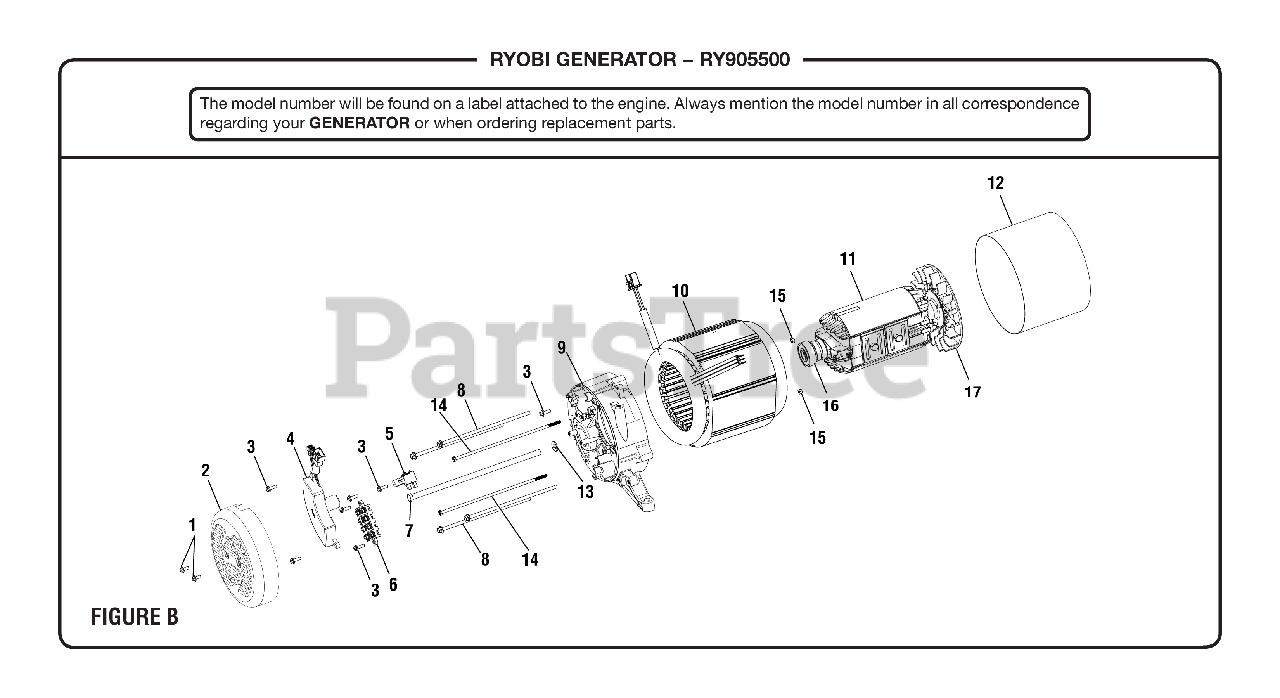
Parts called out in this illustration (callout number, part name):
1	Bolt (M5 x 12 mm, Hex Flange Hd.)
2	Brush Cover
3	Bolt (M5 x 16 mm, Hex Flange Hd.)
4	Automatic Voltage Regulator
5	Brush Assembly 190 mm
6	Terminal Block
7	Rotor Bolt (M8 x 222 mm, Flange Hex Hd.)
8	Stator Bolt (M6 x 180 mm, Flange Hex Hd.)
9	Bearing Support
10	Stator Assembly
11	Rotor Assembly
12	Generator Head Cover
13	Washer (ID8.4 x OD25.1 x 3t)
14	Bolt (M5 x 200 mm, Hex Hd.)
15	Hex Nut (M5)
16	Ball Bearing (190 mm)
17	Fan (190 mm)
